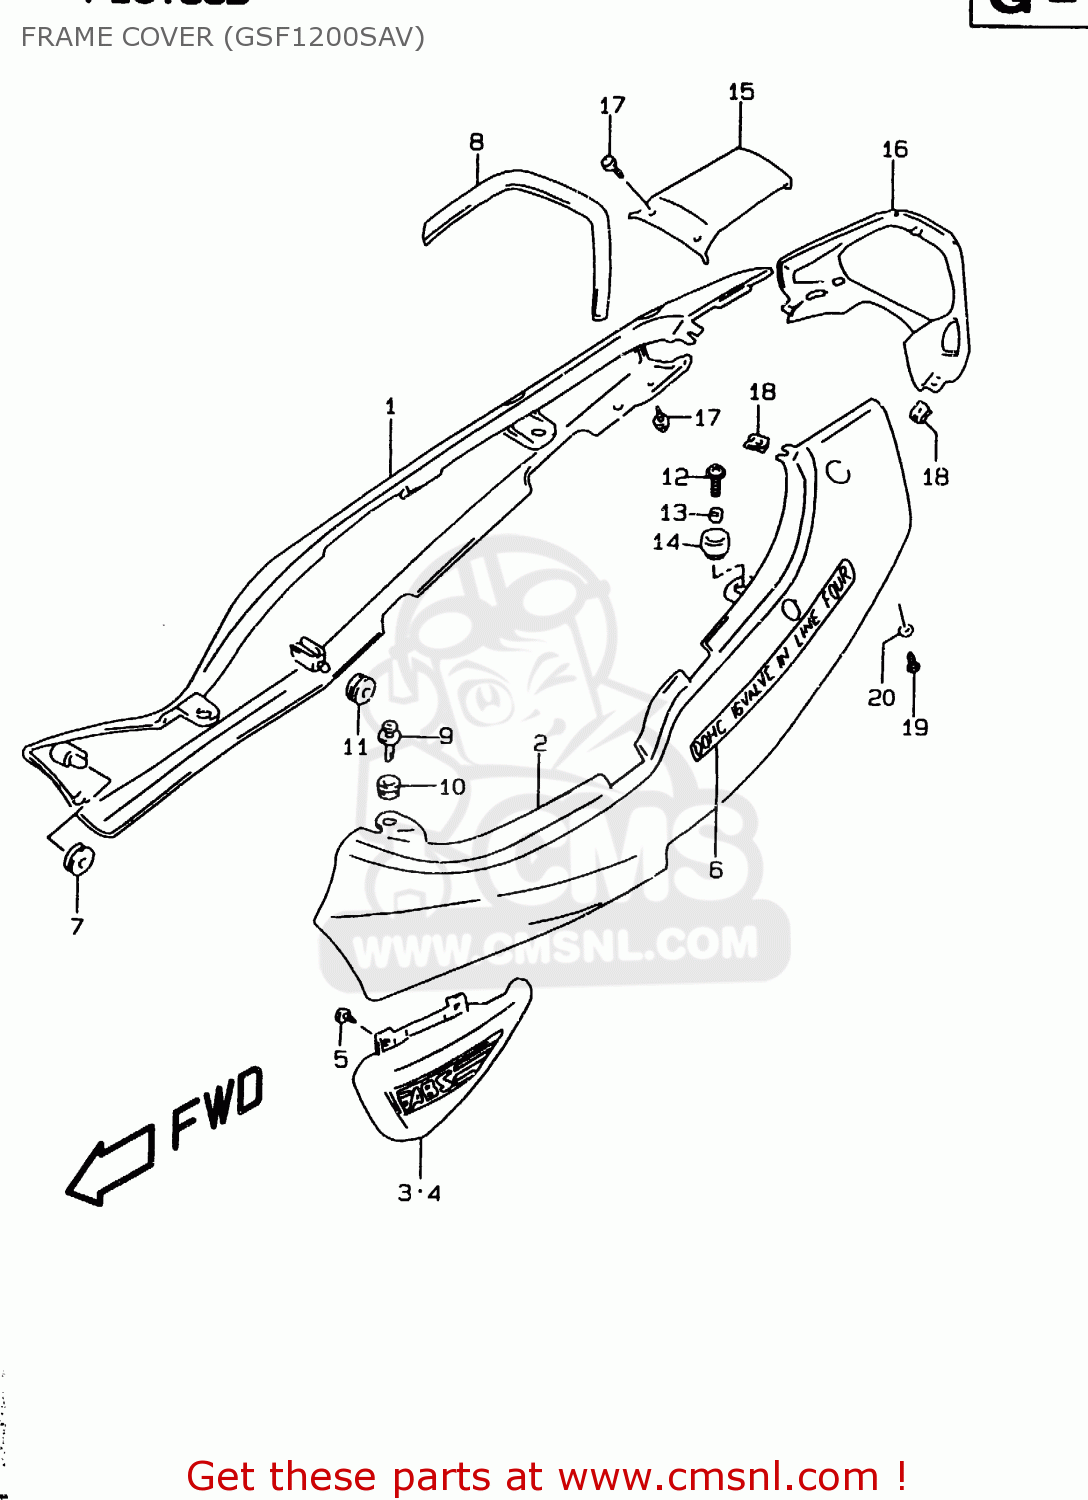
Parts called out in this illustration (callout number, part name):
1	COVER,FRAME,R(BLUE)
2	COVER,FRAME,L(BLACK)
3	COVER,FRAME LWR,R
4	COVER,FRAME LWR,L
5	SCREW
6	EMBLEM,FRAME COVER
7	CUSHION,FRAME COVER FR
8	CUSHION,FRAME COVER UPR
9	CLIP
10	CUSHION
11	CUSHION
12	SCREW(6X20)
13	SPACER(6.5X10X9.4)
14	CUSHION
15	COVER,FRAME CTR
16	COVER,FRAME RR
17	SCREW
18	NUT
19	SCREW
20	WASHER(6.3X16X1.5)
